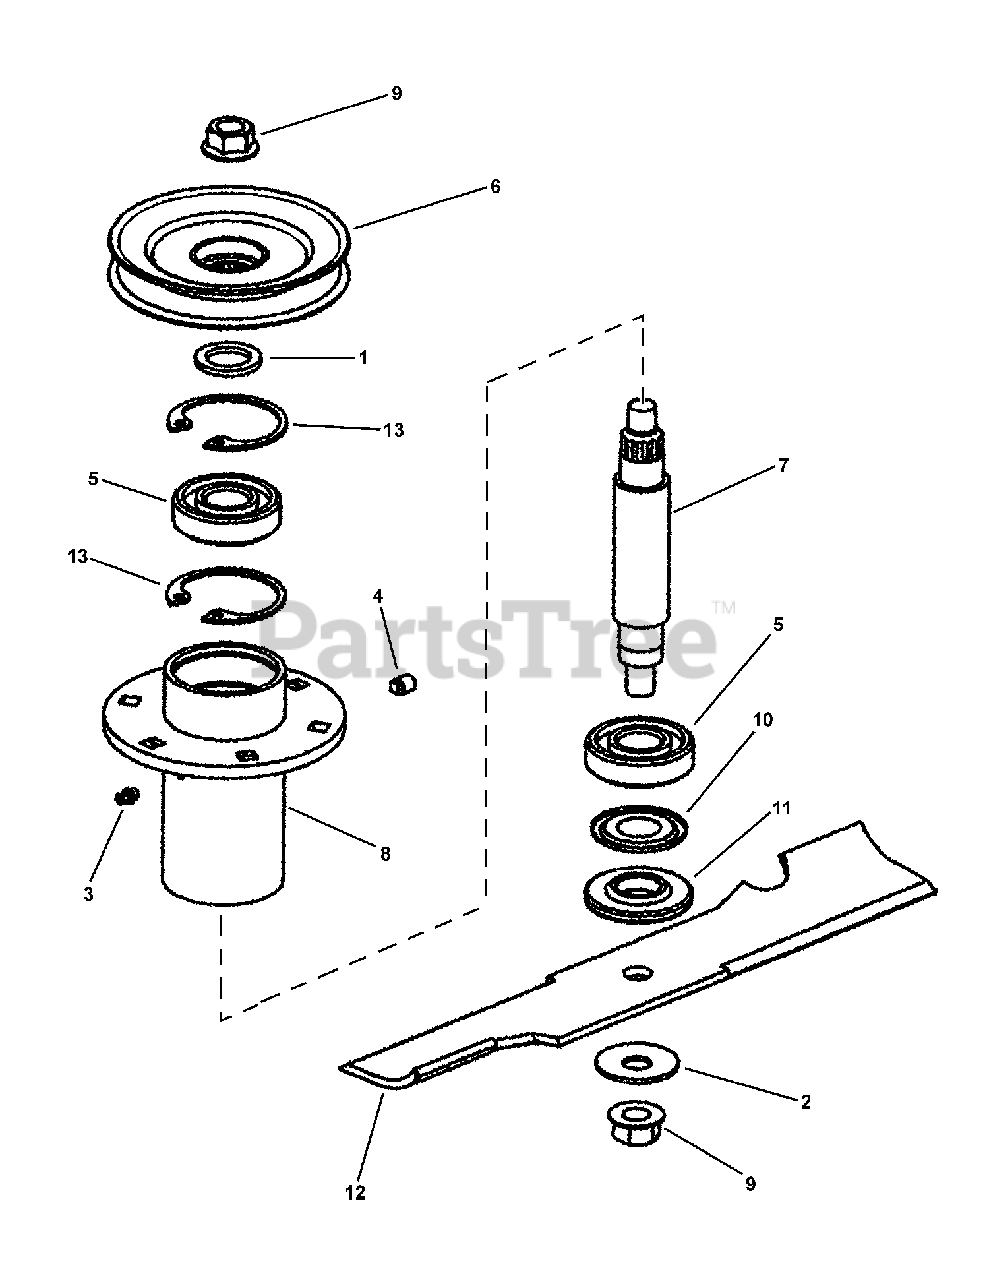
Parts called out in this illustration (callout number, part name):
1	WASHER
2	WASHER, Beveled
3	LUBE FITTING, 1/4-28 Thread Forming
4	GREASE VENT, Spindle
5	BALL BEARING
6	PULLEY, Driven 48" CZT
7	SHAFT, Spindle
8	WELDMENT, 48" Spindle
9	NUT, 5/8-11 Hex Flange Lock, GR 5
10	SEAL, Nylos
11	WASHER, Spindle
12	BLADE, 16-1/2"
13	RETAINING RING, Internal
